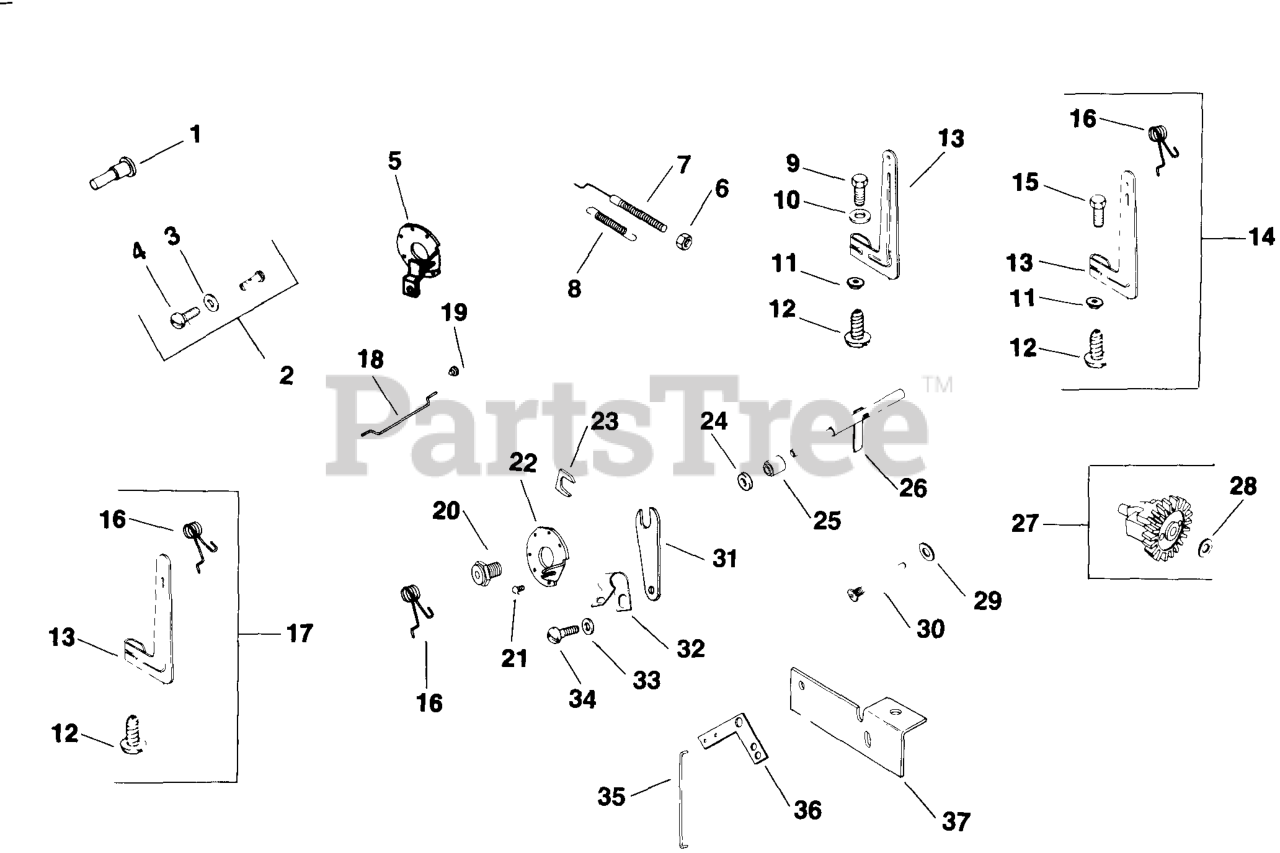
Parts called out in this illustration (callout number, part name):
11	PALNUT, 1/4-20
12	SCREW, WSH HD TAP #8-32X1/4" USE 25 086 96-S
13	LEVER, GOVERNOR
14	LEVER - DISCONTINUED
15	SCREW, WSH HD 1/4-20X7/8" - DISCONTINUED
18	LINKAGE
20	BUSHING - (#DSC)
21	SCREW, DRIVE USE 25 086 86-S
22	DISC, GOVERNOR REGULATING
26	KIT,SHAFT
27	KIT, GOVERNOR GEAR
30	PIN
31	BRACKET, SUPPORT - DISC.
31	CONTROL, HAND SPEED - (#DSC)
